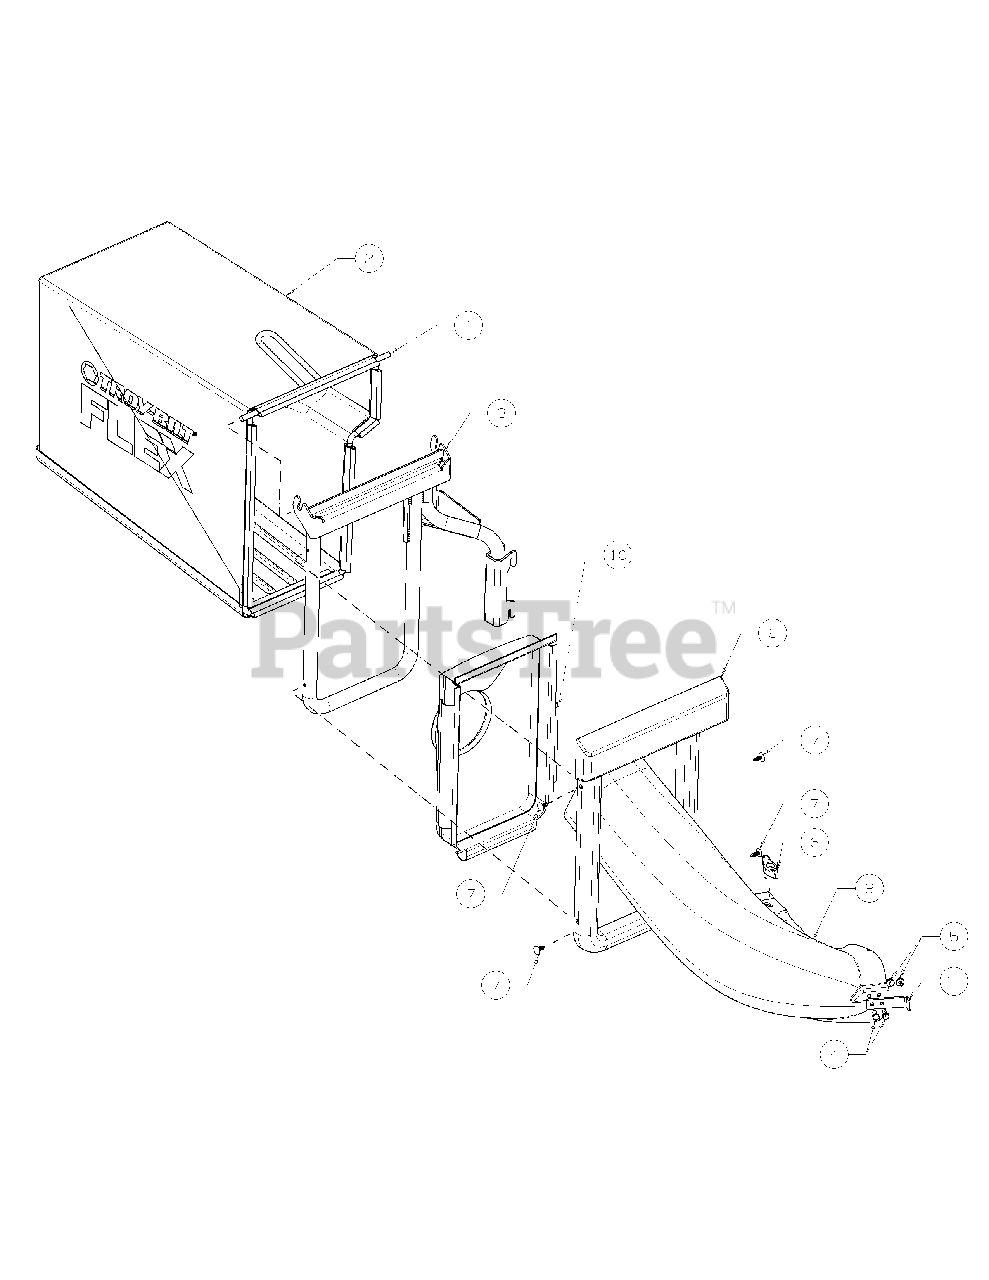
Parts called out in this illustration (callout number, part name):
1	GRASS BAG FRAME FLEX
2	GRASS BAG FLEX
4	SCREW-1/4-20 X .62
6	KNOB-WING 5/16-18
7	RATCHET CLIP .250
8	DISCHARGE BAGGER CHUTE FLEX
9	FRONT PANEL BAGGER COVER FLEX
10	FRONT PANEL BAGGER FLEX
11	DISCHARGE BOOT MOUNT BRKT FLEX
